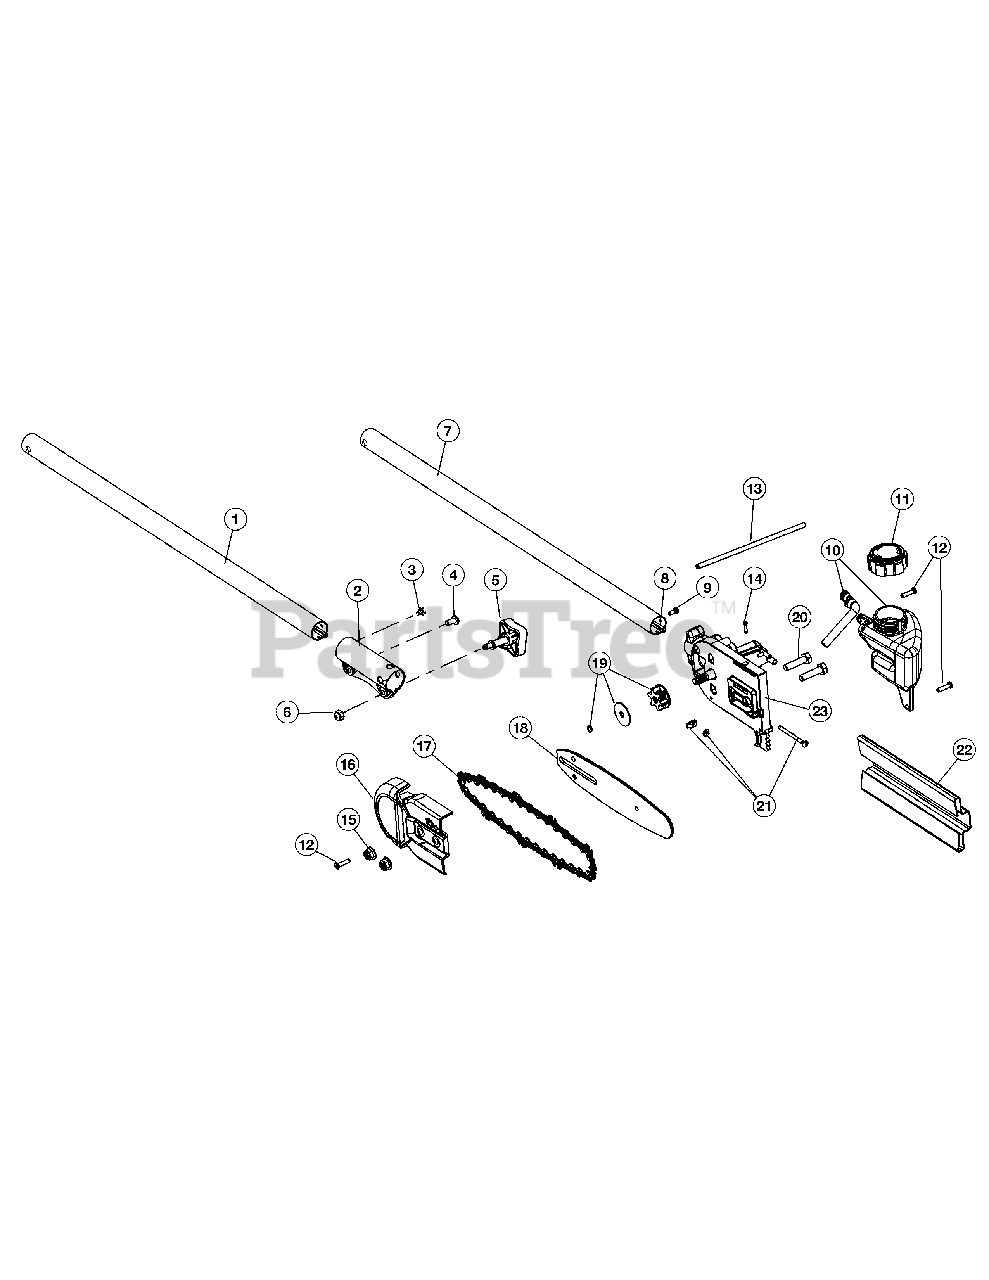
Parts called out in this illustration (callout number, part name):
1	Extension Boom
2	Split Boom Coupler (Incl. 3-6)
5	Adjustment Knob
6	Knob Retaining Nut
7	Drive Shaft Housing (Incl. 8)
8	Flexible Drive Shaft
9	Screw
10	Oil Tank Assembly
11	Fuel Cap Assembly
16	Chain Guard
19	Sprocket Assembly
21	Chain Tension Hardware Assembly
22	Chain Cover
23	Gearbox Assembly (Incl. 14 & 19)
